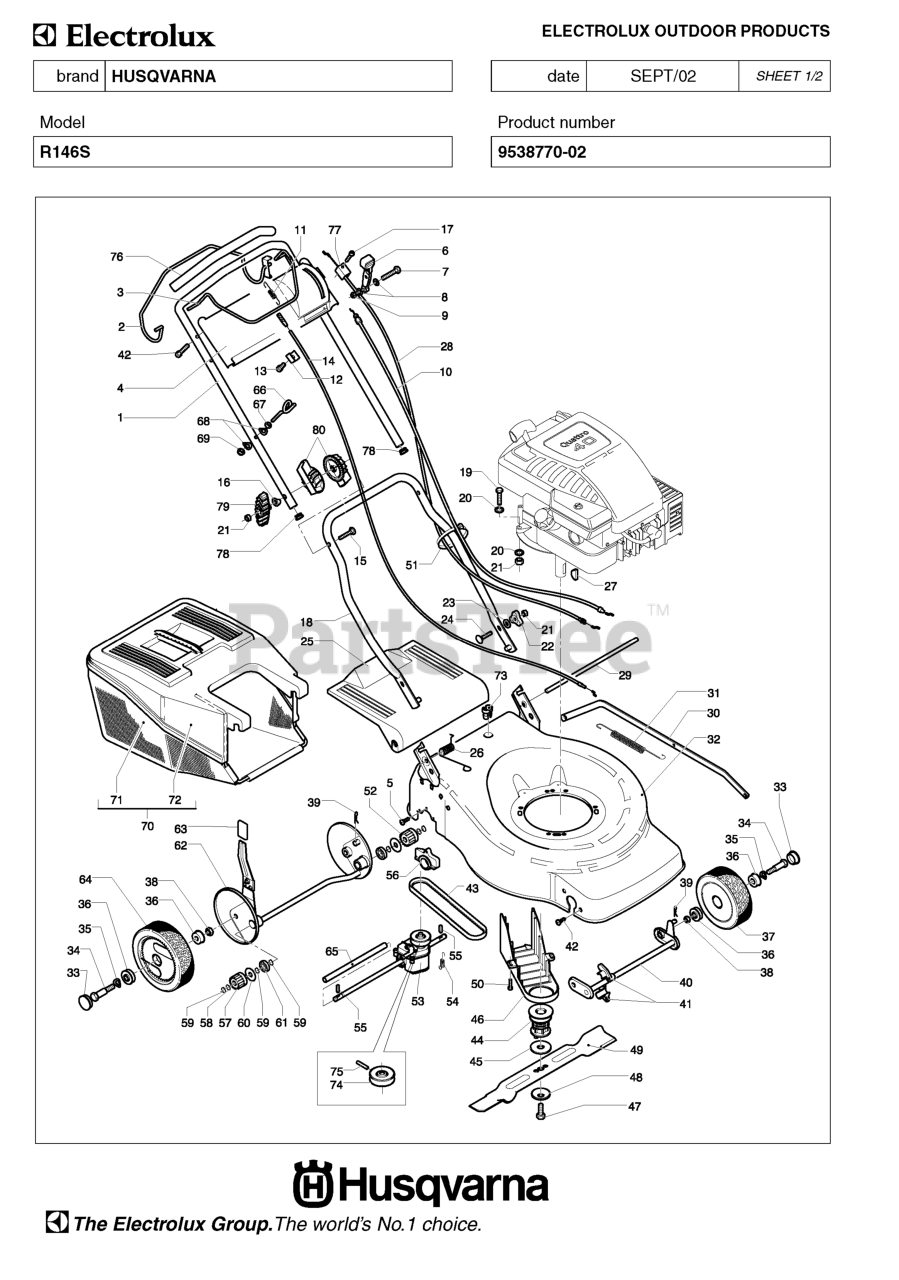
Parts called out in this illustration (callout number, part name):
24	Screws
50	Screws
59	Washers
